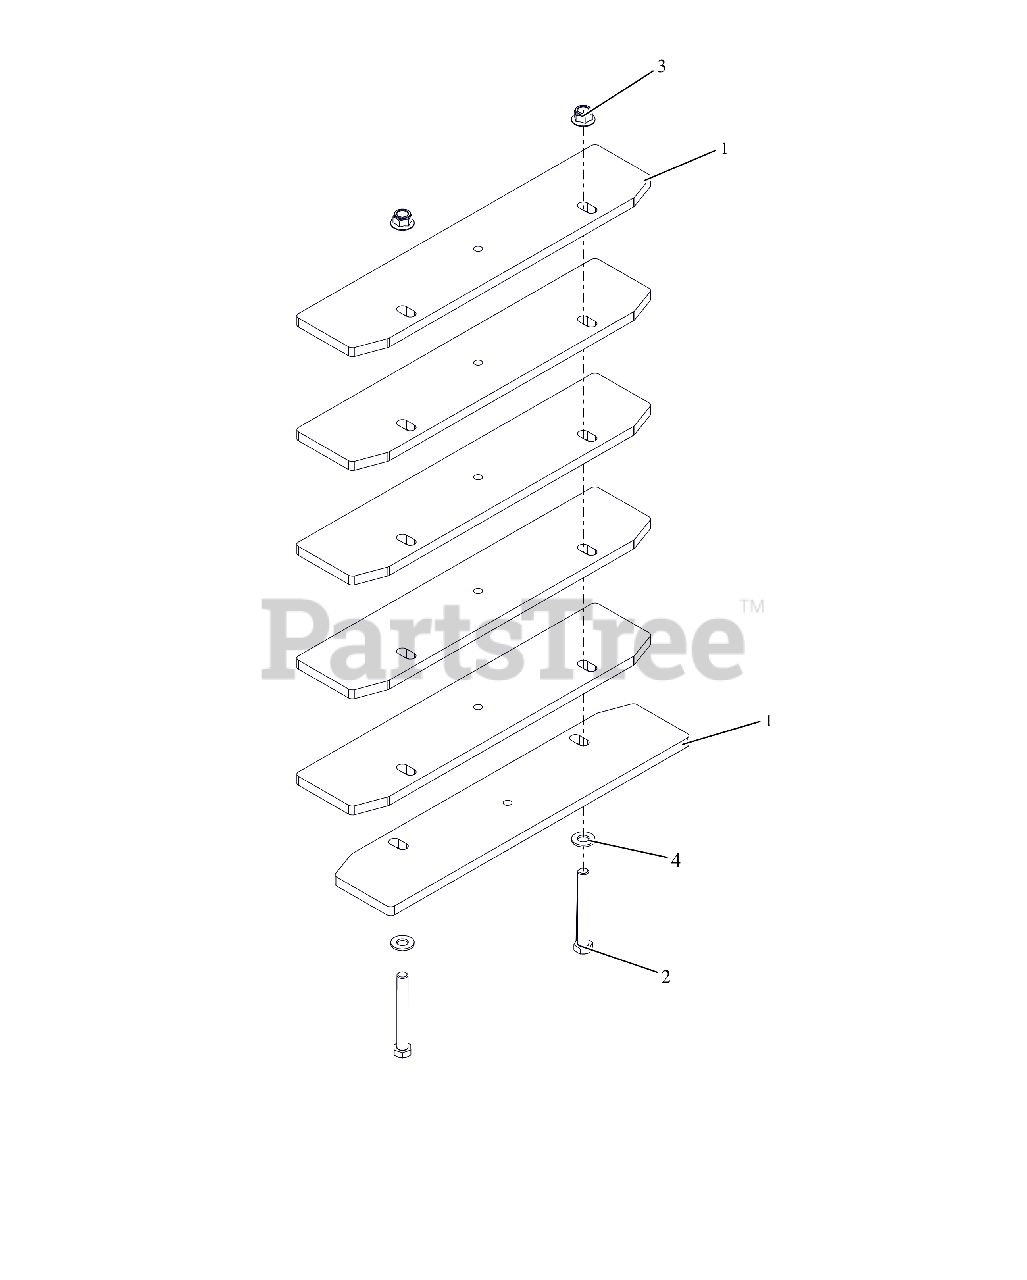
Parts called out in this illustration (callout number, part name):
1	PLATE, COUNTER WEIGHT
2	@BLT-HEX .50-13X4.00 GR5 YWZC
3	@NUT-LK-NYL-FLG .50-13 YWZC
4	@WSHR-FL-STL.531X1.06X.095YWZC
